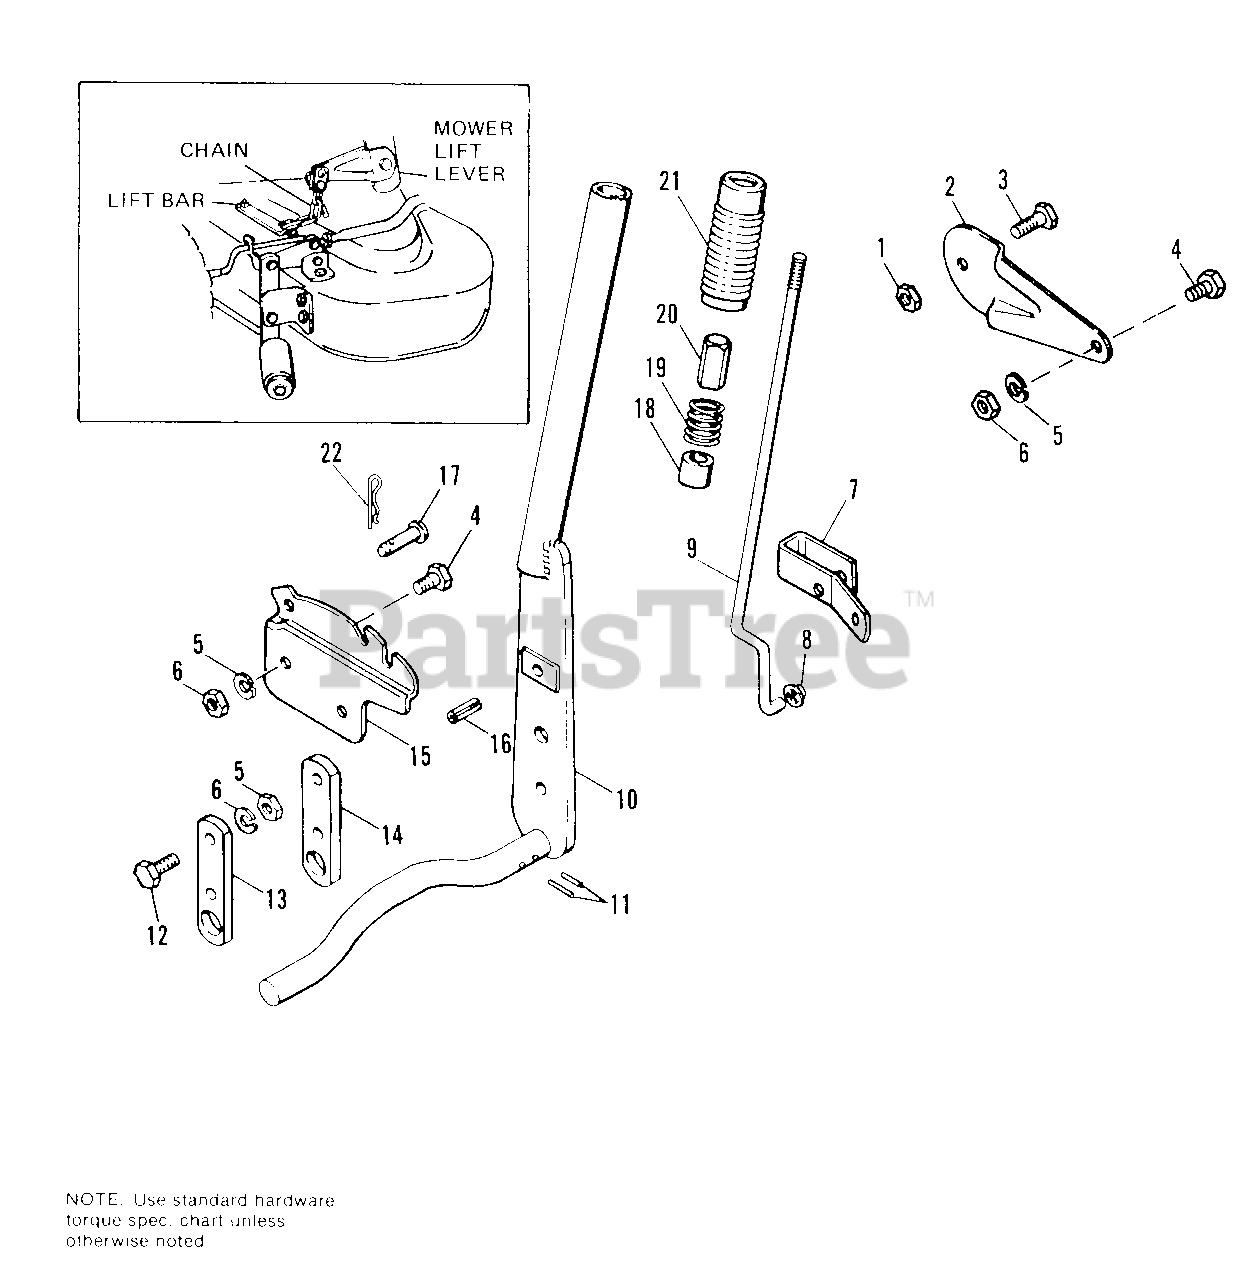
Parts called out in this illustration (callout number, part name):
1	LOCKNUT, Hex, 3/8-16
2	LEVER, Lift, Mower
3	CAPSCREW, Hex Hd., 3/8-16 x 7/8
4	CAPSCREW, Hex Hd., 3/8-16 x 3/4
5	LOCKWASHER 3/8
6	NUT, Hex, Full, 3/8-16
7	LATCH, Lift Lever
9	ROD Lift Lever
9	ROD, Lift Lever
10	LEVER ASSY., Lift
11	PIN, Roll, 3/16 x 1
12	CAPSCREW, Hex Hd., 3/8-16 x 1
13	BAR, Bearing, L.H.
14	BAR, Bearing, R.H.
15	QUADRANT, Lift Lever
16	PIN, Roll, 3/8 x 1
20	BUTTON, Thumb
21	GRIP, Handle
22	CLIP, Hair Pin (990486 & 990542 Only)
